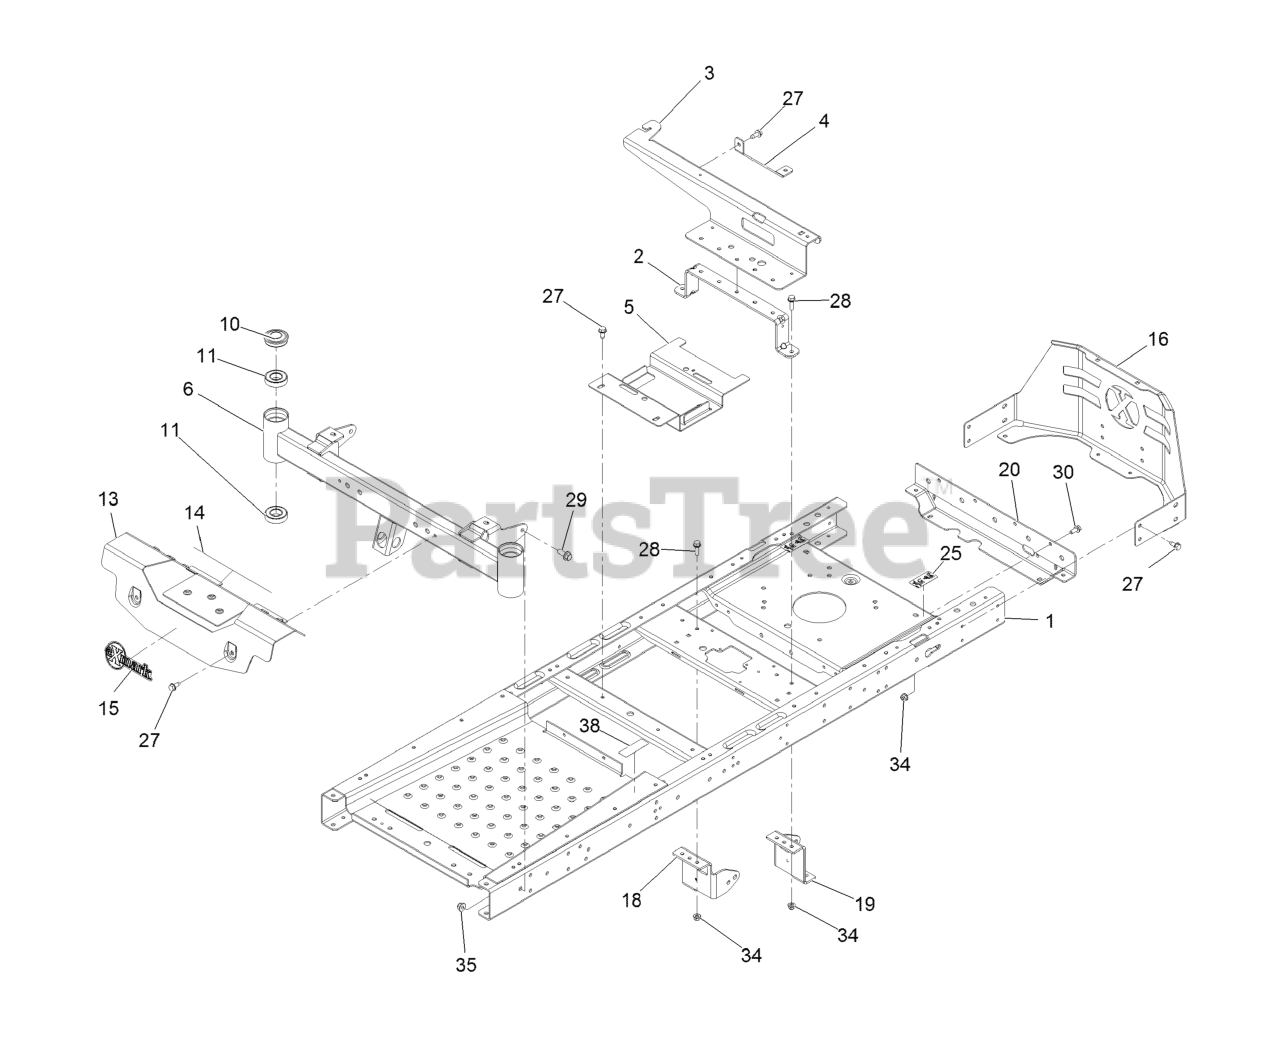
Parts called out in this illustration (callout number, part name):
1	FRAME ASM
2	BRACE-SEAT, REAR (NARROW)
3	SUPPORT-POD
4	SUPPORT-TANK, REAR
5	BRACKET-BATTERY
6	AXLE-FRONT, NARROW
10	Cap-Grease
11	BEARING-BALL
13	FOOTREST ASM
14	DECAL-WARNING
15	DECAL-EXMARK LOGO
16	GUARD-ENGINE, NARROW
18	MOUNT-HYDRO, FRONT (RIGHT
19	Mount-Hydro, Front (Left)
20	CROSSMEMBER-REAR, NARROW
25	DECAL-BYPASS
27	Screw-HWH 5/16-18 X 3/4 Tf
28	SCREW-HHF
29	SCREW-HHF 3/8-16 X 1
30	SCREW-HHF
34	NUT-HF, NI
35	NUT-HF, NI
38	DECAL-BRAKE, PARKING
